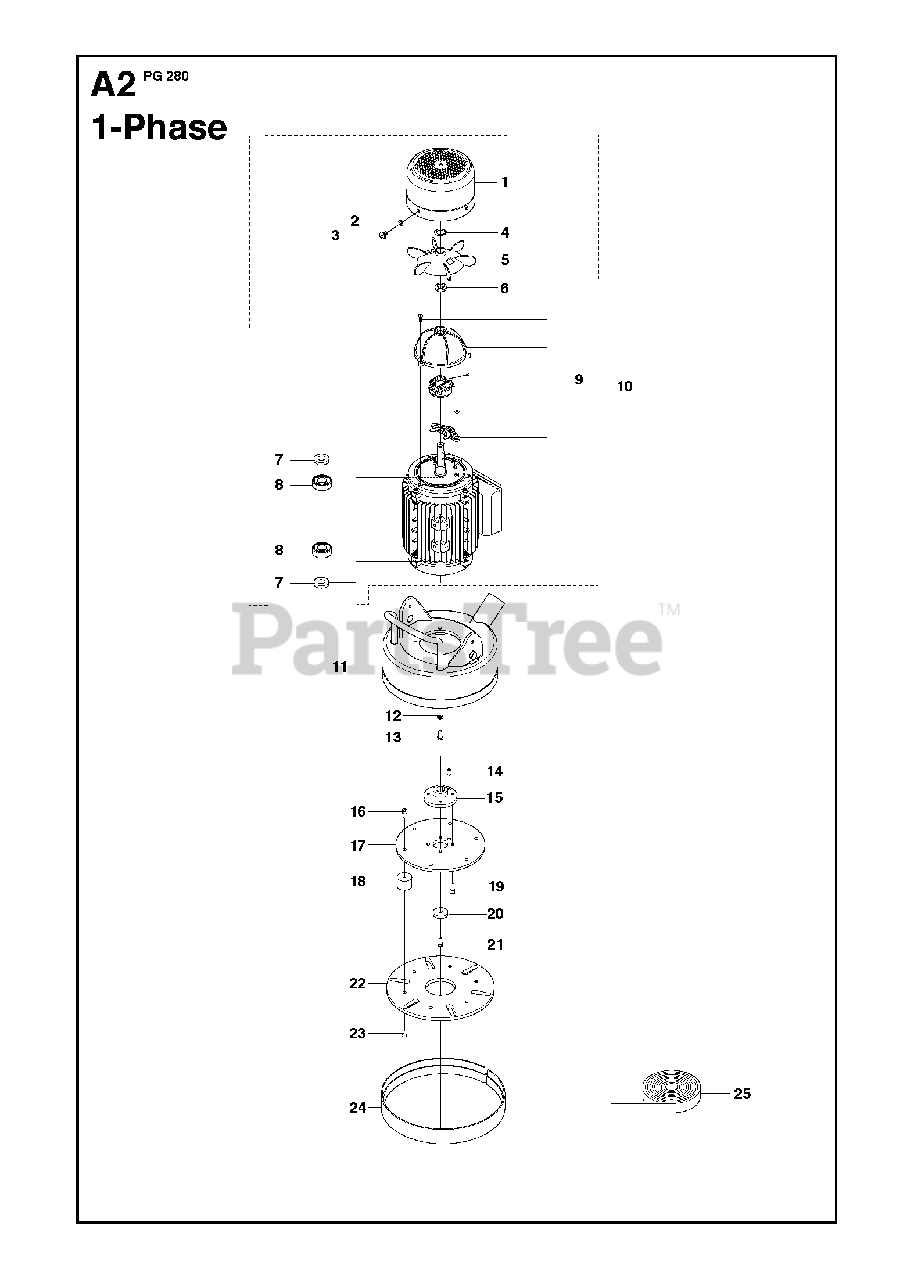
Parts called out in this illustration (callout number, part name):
9	CENTRIFUGAL CLUTCH100-120V, 60Hz, US/CAN/JP
9	CENTRIFUGAL CLUTCH200-230V, EU/AUS
9	CENTRIFUGAL CLUTCH200-230V, US/CAN/Brazil
9	CENTRIFUGAL CLUTCH100-120V, 50Hz, UK/JP
10	MOTOR200-230V, EU/AUS
10	MOTOR100-120V, 60Hz, US/CAN/JP
10	MOTOR100-120V, 50 Hz, UK/JP
12	WASHER
